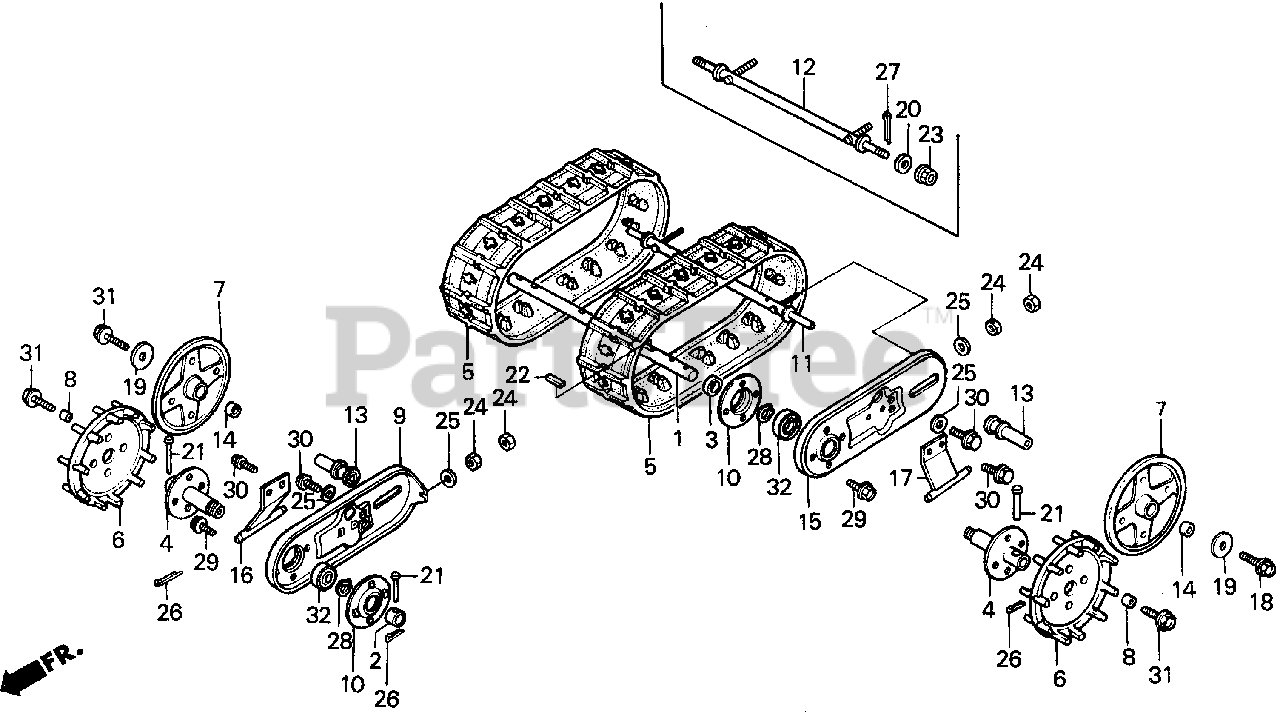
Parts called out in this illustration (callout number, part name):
1	SHAFT, WHEEL
2	COLLAR, WHEEL SHAFT
3	COLLAR, WHEEL SHAFT (B)
4	HUB, CRAWLER
5	CRAWLER (NOT AVAILABLE)
6	SPROCKET, CRAWLER
7	ROLLER, CRAWLER (NOT AVAILABLE)
8	COLLAR, SPROCKET (NOT AVAILABLE)
9	PLATE, R. CRAWLER
10	HOLDER, CRAWLER BEARING
12	PIPE, CRAWLER (NOT AVAILABLE)
13	SHAFT, ROLLER (NOT AVAILABLE)
14	BUSH, ROLLER
15	PLATE, L. CRAWLER
16	GUIDE, R. CRAWLER
17	GUIDE, L. CRAWLER
20	WASHER (12MM) (NOT AVAILABLE)
21	PIN (6.2X38)
22	KEY (5X5X21)
23	NUT, CASTLE (12MM)
24	NUT, HEX. (8MM)
25	WASHER, PLAIN (8MM)
26	PIN, COTTER (3.0X18)
27	PIN, COTTER (3.0X45)
28	CIRCLIP (OUTER) (25MM)
29	BOLT, FLANGE (6X10)
30	BOLT, FLANGE (8X14)
31	BOLT, FLANGE (8X20)
32	BEARING, RADIAL BALL (6005UU)
